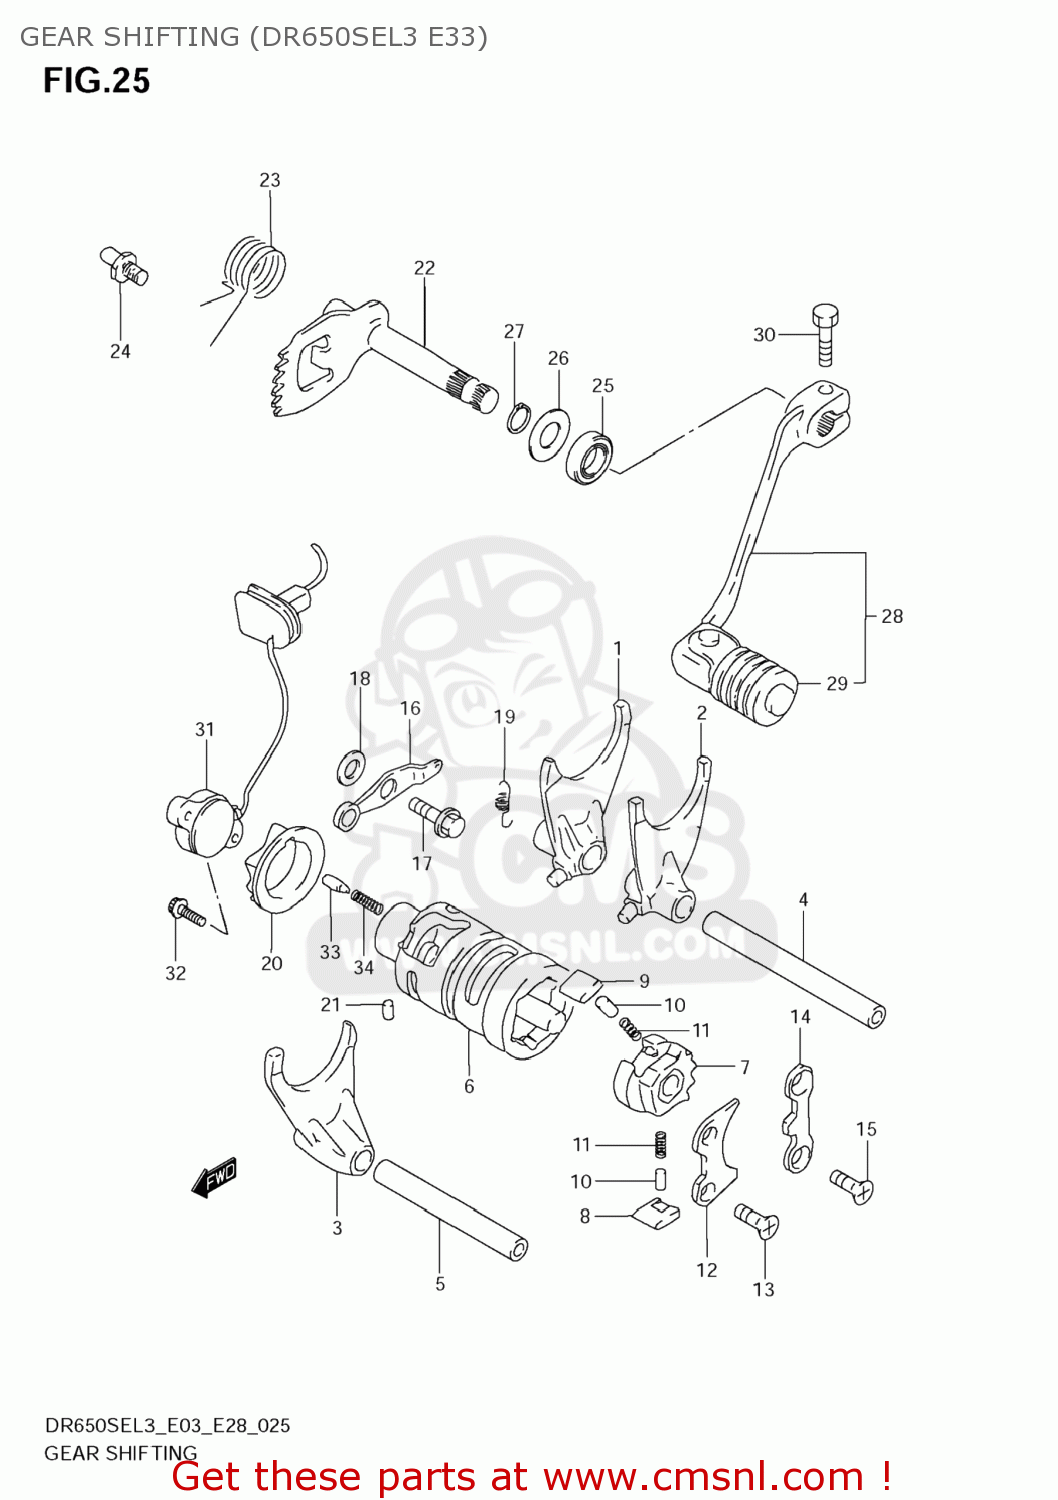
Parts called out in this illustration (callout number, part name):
1	FORK,GEAR SHIFT NO.1
2	FORK,GEAR SHIFT NO.2
3	FORK,GEAR SHIFT NO.3
4	SHAFT,GEAR SHIFT FORK
5	SHAFT,GEAR SHIFT FORK
6	CAM,GEAR SHIFT
7	GEAR,GEAR SHIFT CAM DRIVEN
8	PAWL,GEAR SHIFT NO.1
9	PAWL,GEAR SHIFT NO.2
10	PIN(5X8)
11	SPRING
12	LIFTER,GEAR SHAFT PAWL
13	SCREW(6X12)
14	STOPPER,GEAR SHIFT POLE
15	SCREW(6X12)
16	STOPPER,GEAR SHIFT CAM
17	BOLT(6X14.6)
18	WASHER
19	SPRING
20	PLATE,GEAR SHIFT CAM STOPPER
21	PIN
22	SHAFT,GEAR SHIFT
23	SPRING
24	STOPPER,GEAR SHIFT ARM
25	SEAL,OIL (12X22X9)
26	WASHER
27	CIRCLIP
28	LEVER ASSY,GEAR SHIFT
29	RUBBER,GEAR SHIFT PEDAL
30	BOLT
31	BASE ASSY,NEUTRAL SW TERMINAL
32	BOLT
33	PIN(5X15.5)
34	SPRING
